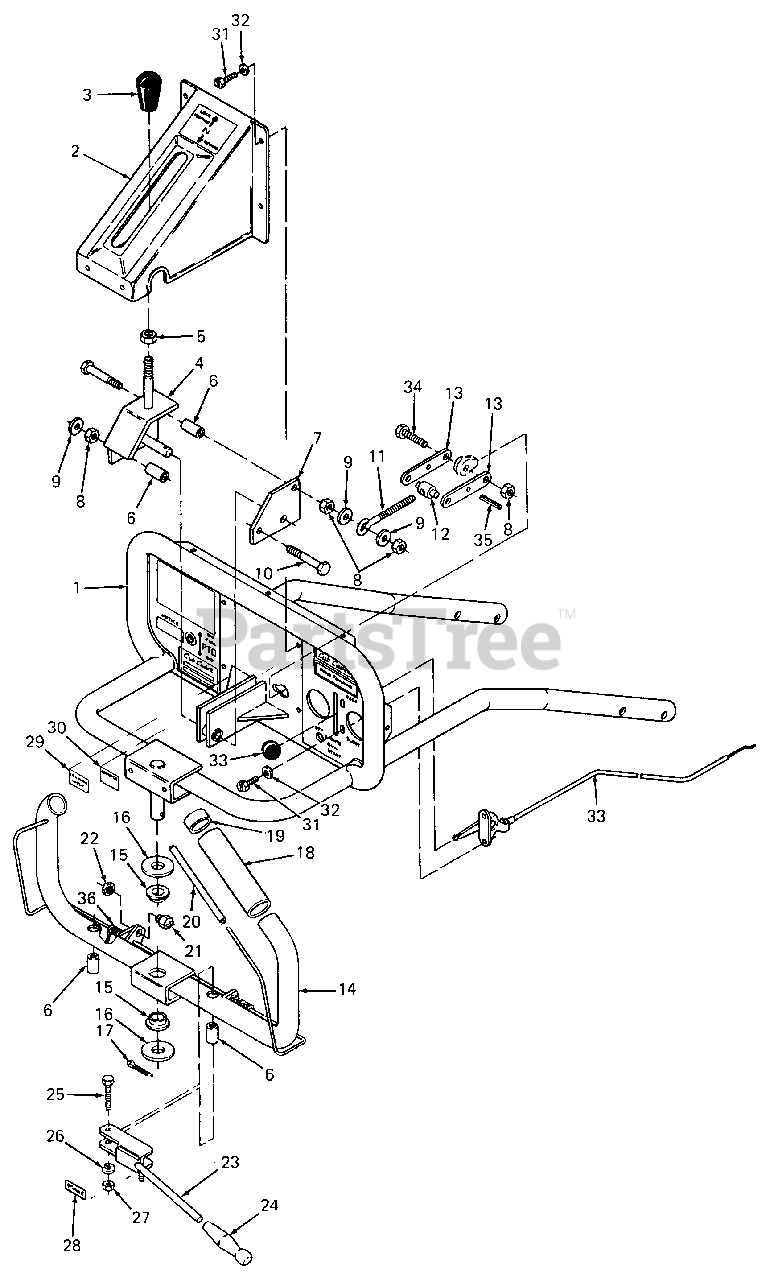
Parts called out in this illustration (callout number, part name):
1	Handlebar Assy
2	Cover, Shifter w/Graphics
3	Knob, Control
4	Shifter, Forward-Reverse
5	Nut, Hex Jam, 1/2-13
7	Plate, Shifter
8	Nut, Hex Center Lock, 3/8-16
9	Washer, Flat, .406 X .74 X .063 Thk
10	Screw, Hex Cap, 3/8-16 X 2.75 Lg GR2
11	Eyebolt, Cable
12	Swivel, Cable
13	Link, Cable
14	Steering Handle
15	Bushing, Flanged
16	Washer, Flat, .812 X 1.38 X .100 Thk
17	Pin, Cotter, 3/16 X 1.75 Lg
18	Grip, Handle
20	Grip, Operator Presence
21	Switch, Safety
22	Nut, Switch
23	Brake Lever
24	Grip, Brake Handle
25	Screw, Hex Cap, 3/8-16 X 2.0 Lg GR5
26	Washer, Lock, 3/8
27	Nut, Hex Center Lock, 3/8-16
28	Decal, Brake
29	Decal, Forward
30	Decal, Reverse
31	Screw, Hex Hd Tapp, 1/4 X .75 Lg
32	Washer, Flat, .281 X .750 X .030 Thk
33	Control, Throttle w/Knob
34	Screw, Hex Cap, 3/8-16 X 1.0 Lg GR5
35	Pin, Spiral Spring, 1/4 Dia X 1.0
36	Spring, Torsion
